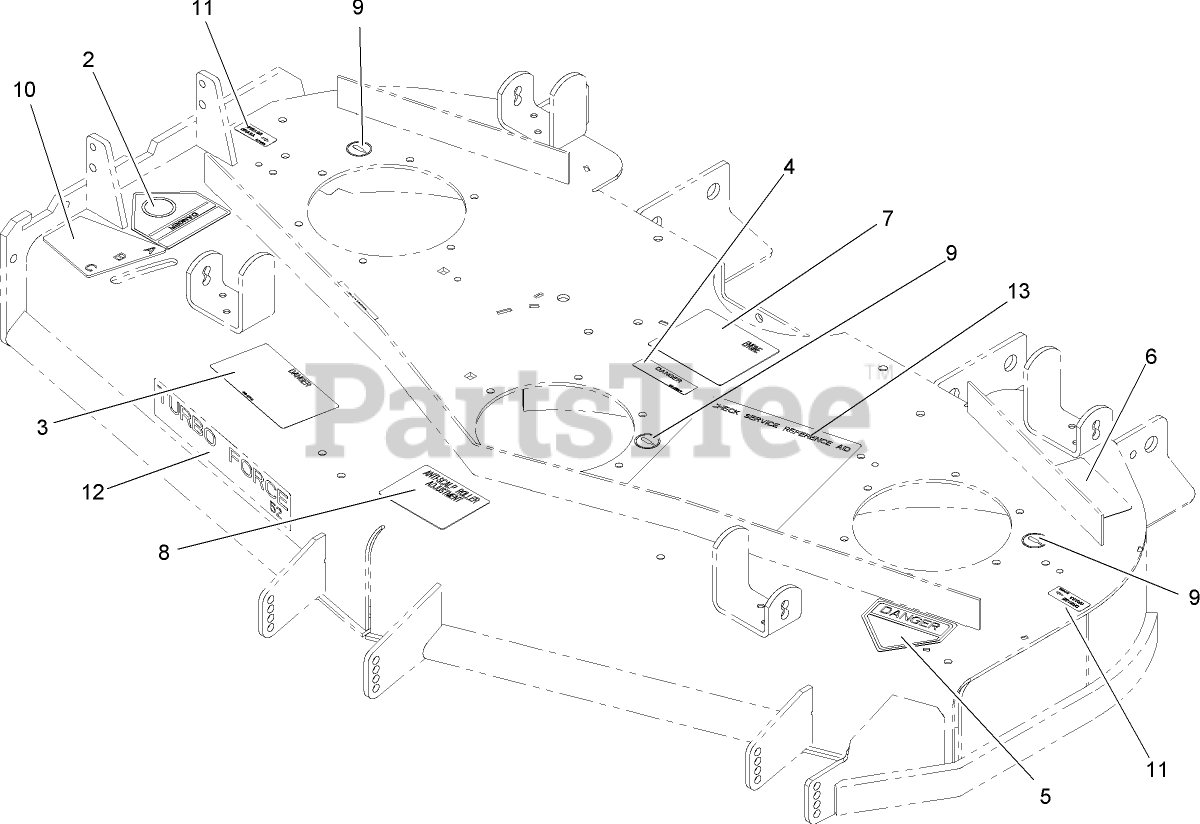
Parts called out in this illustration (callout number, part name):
2	DECAL-DANGER
3	DECAL-DANGER, THROWN OBJECT
4	DECAL-COVER, MISSING
5	DECAL-DANGER
6	DECAL-TORQUE
7	Decal-Routing, Belt
8	DECAL-SCALP, ANTI
9	DECAL-GREASE
10	DECAL-ADJUSTMENT, BAFFLE
11	Decal-Grease
13	Decal-Service, Check
